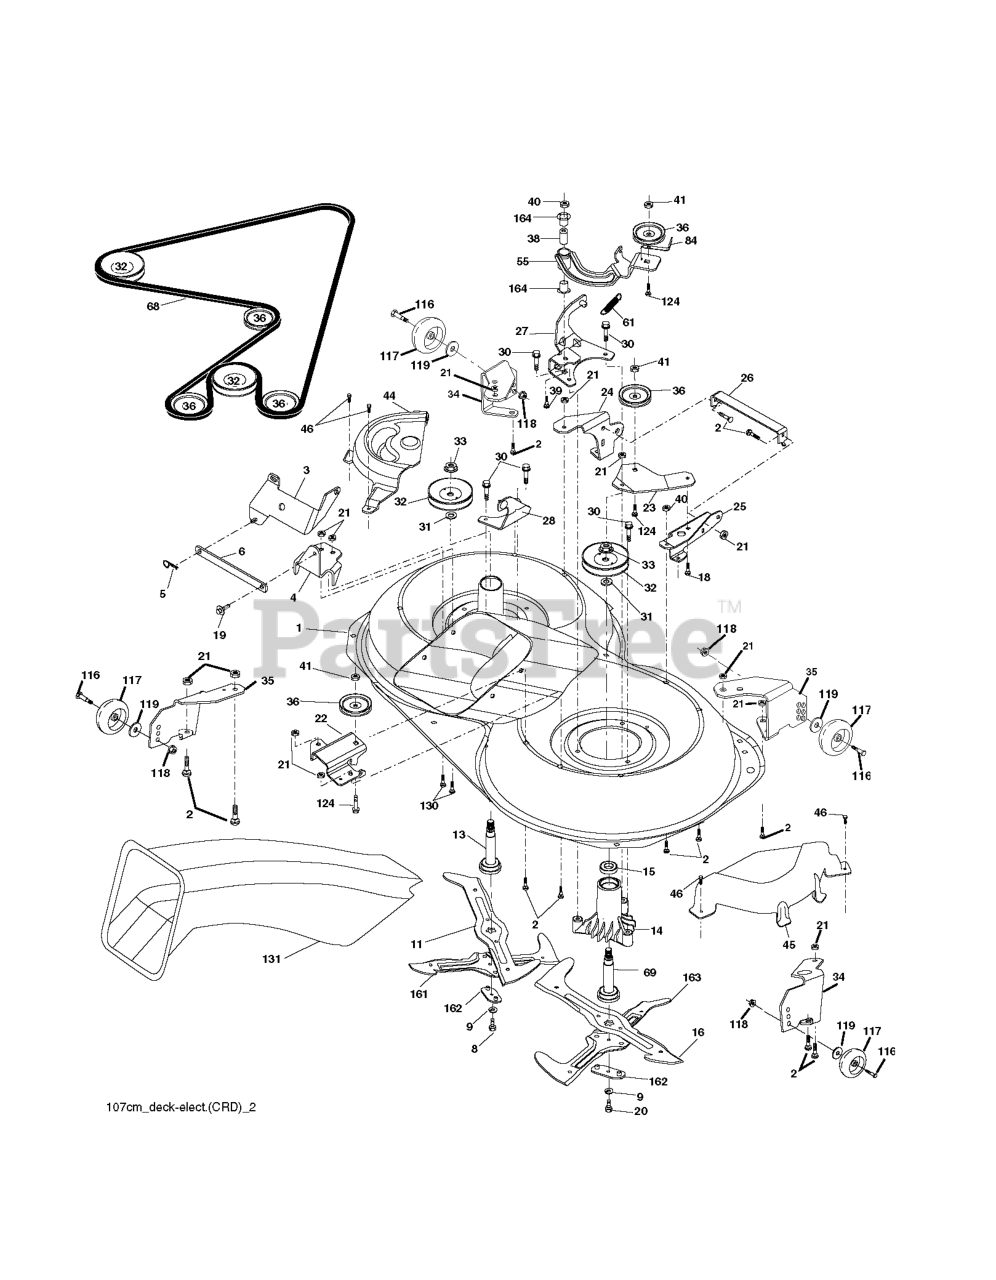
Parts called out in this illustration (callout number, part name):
1	Housing Asm. Mower 107 CRD
2	RP BOLT 5/16-18 X3/4 ZN/YEL GR
5	RETAINER-SPRNG RB
6	BAR.SWAY.92.CRD
8	BOLT.3/8-24X1.25 GR8
9	LOCKWASHER
11	BLADE.3N1.LH.CRD
13	SHAFT.ASM.W/LWR.BRG.RH.THREAD
14	HOUSING.MANDREL.VENTED (MACHD)
16	BLADE.3N1.RH.CRD
19	BOLT SHD 5/16-18
20	BOLT.3/8-24X1.25GR8. LHTHRD
21	LOCKNUT
22	BRACKET.IDLER.RR.107.CRD
24	BRACKET
25	BRACKET RF
26	SUPPORT
28	BRACKET
30	SCREW, WASHER HEAD
31	WASHER.SPACER.MANDREL
32	PULLEY.MANDREL.4.80 PD.2006
33	NUT.FLANGE.LOCK.TOP
34	BRACKET
35	BRACKET
36	PULLEY.IDLER.4.25
41	NUT LOCK FLG 3/8-16 UNC
45	COVER.MANDREL.RH.CRD
46	SCREW.1/4-20X5/8
55	ARM.IDLER.107.CRD
61	SPRING
68	HEX-BELT 107 MOWER
69	SHAFT ASM VENT
84	KEEPER, BELT IDLER
116	BOLT.SHOULDER.3/8-16X3-5/8.
117	RP WHEEL. GUAGE RALLY
118	NUT LOCK FLG 3/8-16 UNC
119	WASHER
124	BOLT.3/8-16X1.50
130	BOLT.CARR.SQNK.5/16-18UNC.X3/4
131	CHUTE BAGGER
163	BLADE.CROSS.RH.CRD.107
164	BRNG T
